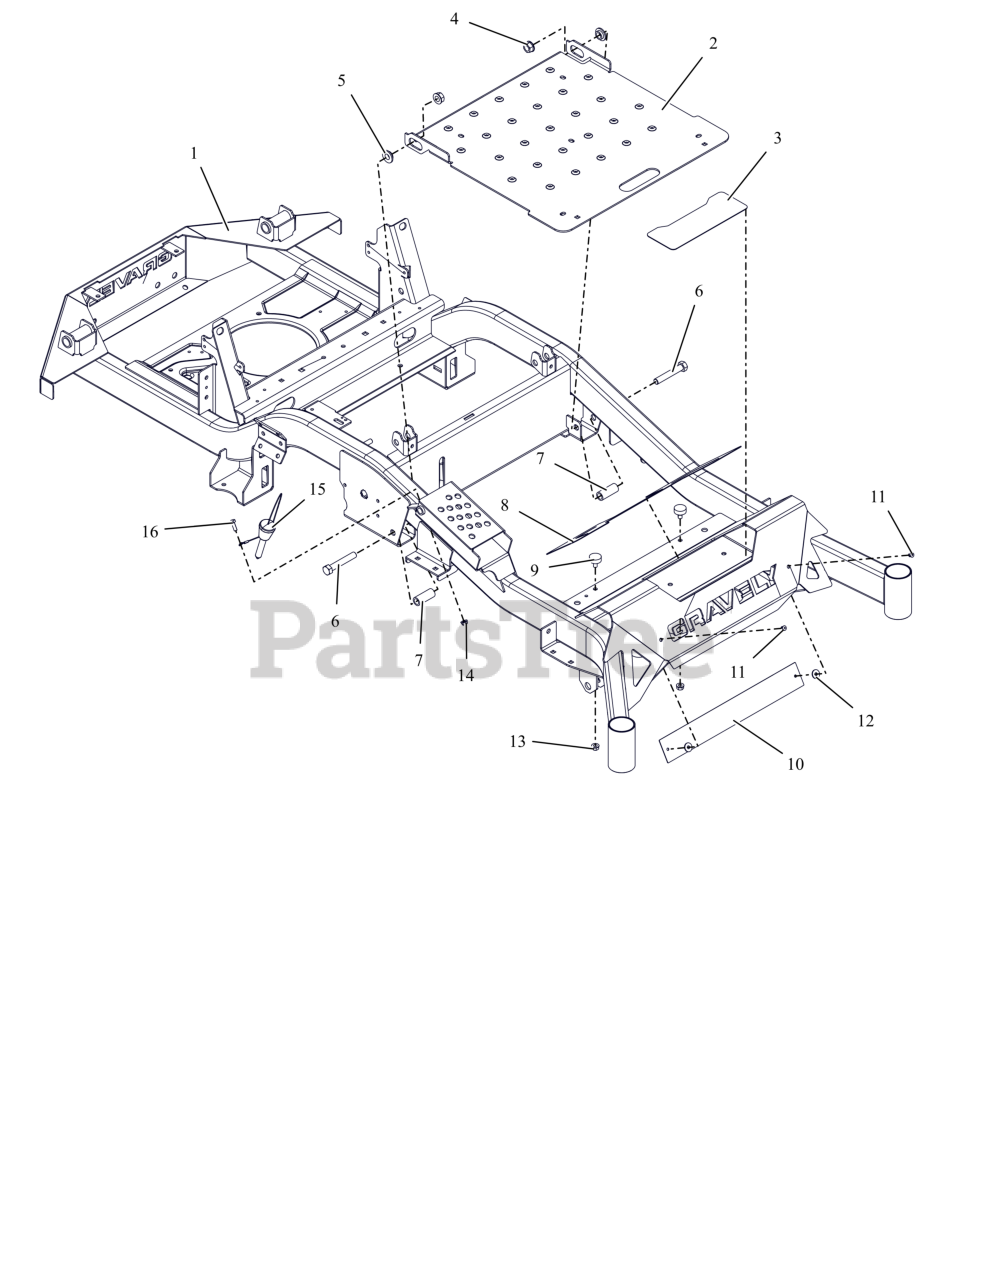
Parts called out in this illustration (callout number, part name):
1	WLDMT, MAIN FRAME -HD 44/52
2	KIT,ACCESS PANEL W/DECALS-RED
3	GRIP, STEP
4	NUT-LK-TOP-FLG .500-13 GF ZCC
5	BSHG-FLG .515X.750X.310X1.120
6	BLT, HEX .50-13X3.00 G5 ZCC
7	SPACER, .515X.75X1.83
8	GRIP, FRONT
9	BUMPER, RUBBER
10	PLATE, BACK FOOT-REST XL
11	RIVET, .1875 AL/AL .126-.250
12	WSHR, RBR W/ADHESIVE .25X.75X.06
13	NUT,SPNLK-FLG .31-18 G5 ZCC
14	NUT,NYL-FLG .25-20 GF ZCC
15	PIN- MAGNETIC .50X2.70
16	BLT, HEX .25-20X.75 G5 ZCC
